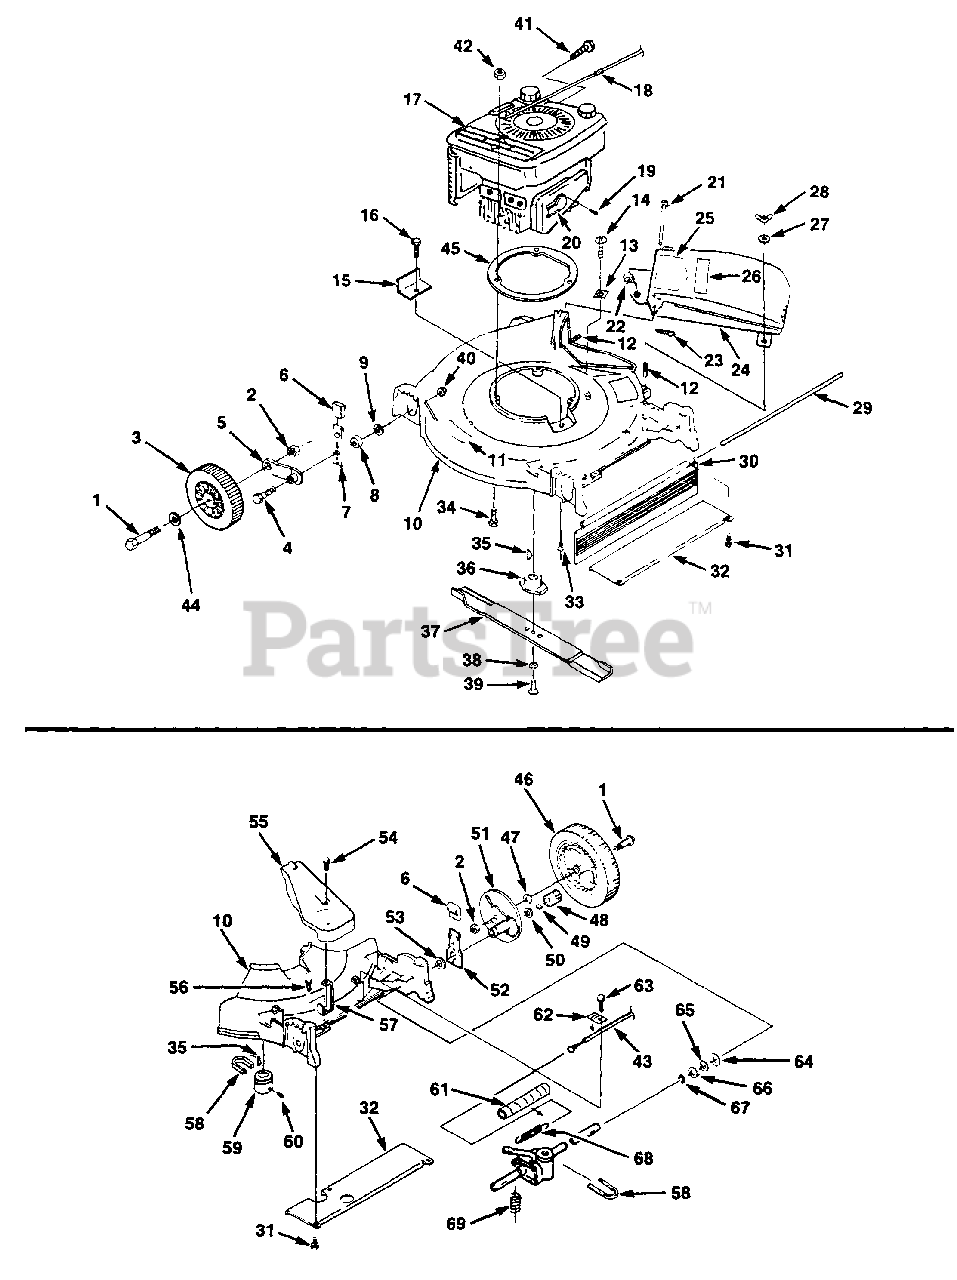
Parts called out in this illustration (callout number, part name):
1	AXLE ASSY.
2	HEX NUT (CM20P4) TBO
3	WHEEL & TIRE
4	Bolt, TBO
5	ARM - Wheel hgt. adj.
6	KNOB
7	Index Front Spring, Tbo
8	SPACER - Wheel hgt. adj.
9	FLAT WASHER(HSD'S) TBO
10	Deck 20" push
11	DECAL- Warning
12	Stud - 1/4-20 x 3/4
13	Bracket - rear bagger
14	SCREW-(1/4-20 X 1/2")
15	COVER- Belt opening
16	SHORT BLK V
18	STOP - Rope
19	Screw (Hex Head)
20	DEFLECTOR
21	Pin - hinge
22	Spring - cover
23	Pin - cotter
24	Cover - discharge opening
25	DECAL-CPSC
26	DECAL- Danger
28	Nut - wing 1/4-20 nylock
29	Rod - drag flap
30	SHIELD TBO
31	SCREW - 1/4-20 x 3/4" Hex Tap
32	Cover - rear
33	Nut - hex 1/4-20 lock
34	Bolt - hex 3/8-16 x 1 1/2
36	ADAPTER- Blade
37	Cutting Blade, 20" Tbo
38	WASHER - Lock 3/8"
39	SCREW TBO
40	HEX WASHER NUT-TBO
41	SCREW
42	NUT- Hex lock (5/16-18)
43	CABLE- Traction control
44	WASHER
45	RING - Engine
46	DRIVE WHEEL TBO
47	WASHER
48	PINION- R.H.
49	PAWL TBO
50	WASHER-TBO
51	DRIVE WHEEL SUPPORT-TBO
52	INDEX SPRING-TBO
53	SPACER - Rear hgt. adj.
54	Screw - phillips 1/4-20 x 3/4
55	Cover - gear reducer
56	Screw - hex 1/4-20 x 9/16 tap
57	Bracket - cover
58	BELT
59	PULLEY- Drive
60	SCREW
61	Cover - spring
62	CLAMP
63	SCREW- 1/4-20 x 5/8"
64	WASHER
65	WASHER
66	WASHER
67	RING TBO
68	SPRING - Ext.
69	SPRING - Compression
